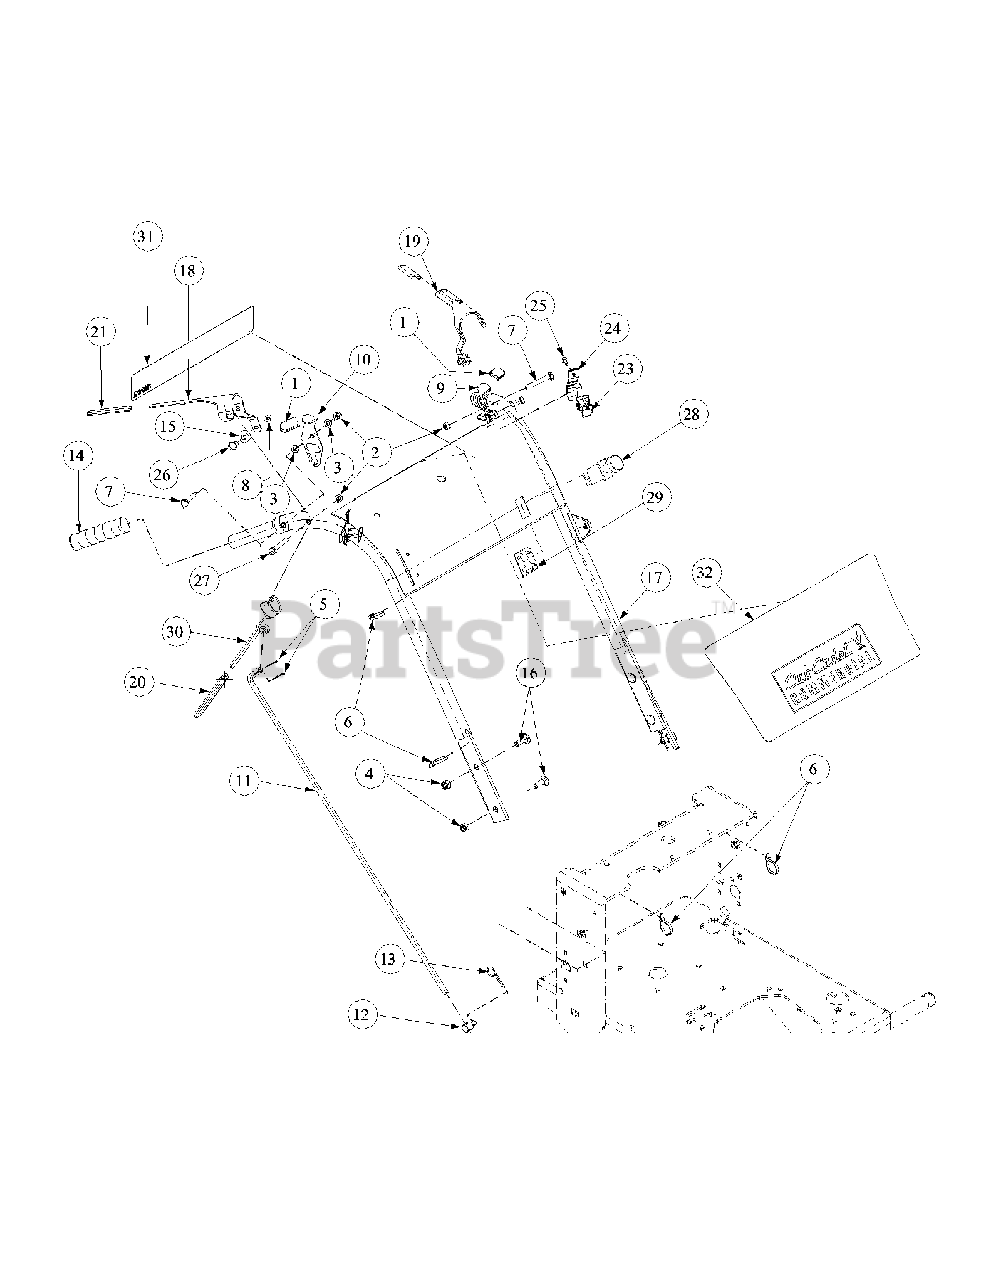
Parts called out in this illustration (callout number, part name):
1	Grip, Neutral Latch, 1.25"
2	Nylock Nut, 5/16-18
3	Flat Washer, 5/16 Zinc
4	Lock Nut, Nylon Insert, 3/8-16
5	Cotter Pin, 3/32 x 3/4, Zinc
6	Cable Tie, 3/16 x .05 x 7.4
7	Hex Cap Screw, 5/16-18 x 2
8	Lock Nut, Nylon Insert
9	Neutral Latch, Left Hand
10	Neutral Latch, Right Hand
11	Steering Control Rod
12	Joint Swivel
13	Hair Pin 3/8-1/2
14	Plastic Handle Grip, Black, 4-5/8
15	Control Rod, Hydro Spacer
16	Carriage Bolt, 3/8-16 x 2
17	Handle Assembly
18	Operator Presence Control RH
19	Operator Presence Control LH
20	Control Sleeve, Black
21	Operator Control Sleeve, Yellow
22	Harness Assembly Adapter (not show)
23	Switch Mounting Snap
24	Operator Presence Return Spring
25	Hex Index Washer Screw, 0.500
26	Shoulder Screw, .38 x .412, 1/4-28
27	Hex Cap Screw, 5/16-18, 2.00
28	Electric PTO Switch
29	PTO Retainer Switch
30	Control Lever Assembly
31	Label Commercial Mower Instruction
32	Gear Label Mower Panel
